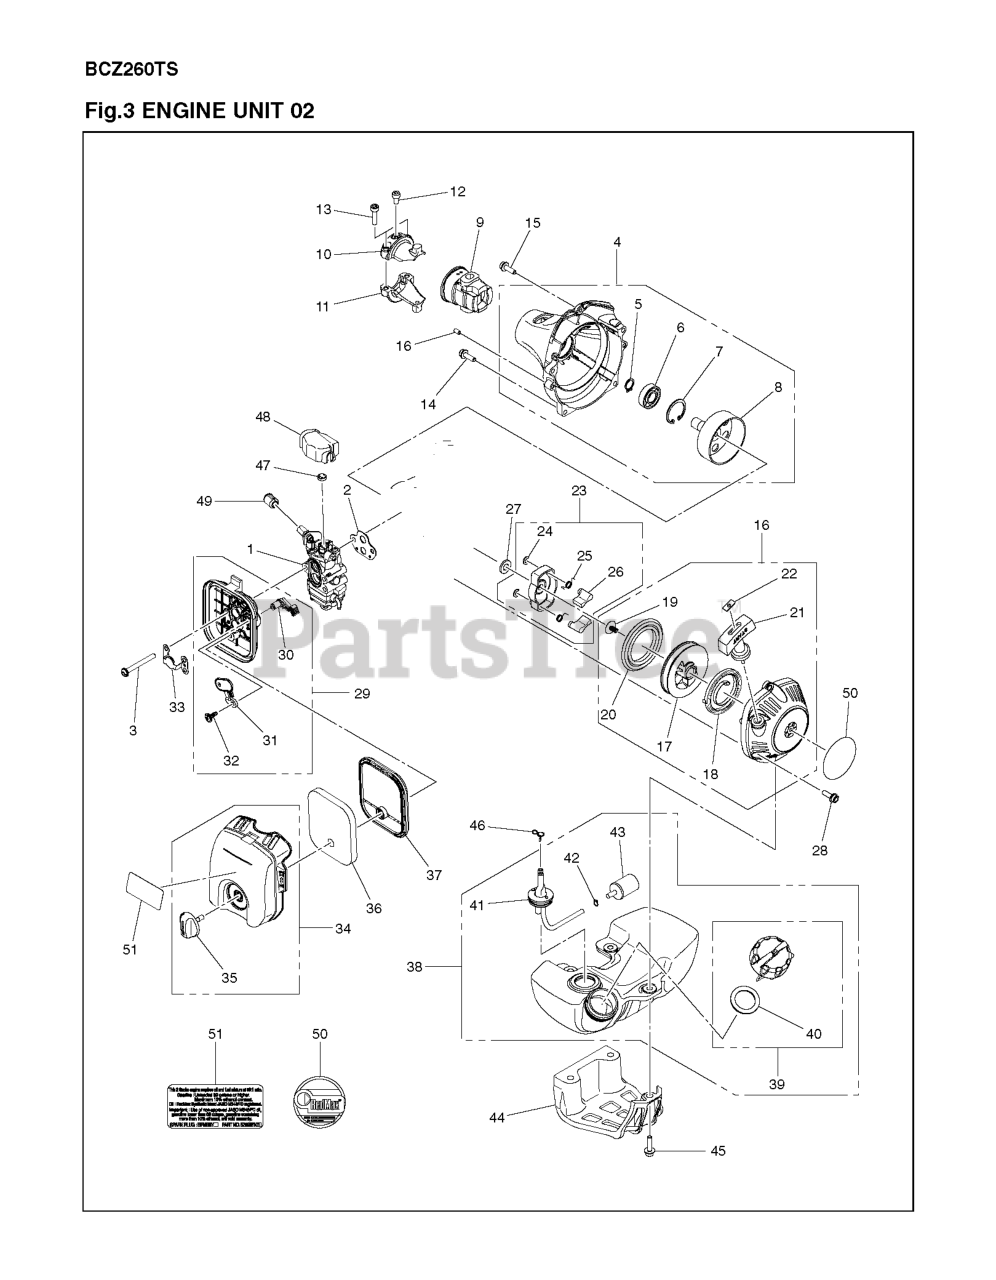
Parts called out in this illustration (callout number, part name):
1	CARBURETOR ASSY
2	GASKET CARBURETOR
4	HOUSING ASSY
8	CLUTCH DRUM
9	CUSHION UPPER
10	BRACKET UPPER M5X0.8
11	BRACKET LOWER
13	BOLT M5X20 T27
14	BOLT M5 X 16
16	STARTER ASSY
17	STARTER PULLEY
18	SPRING, SPIRAL
19	SCREW
20	ROPE
23	STARTER PULLEY ASSY
27	WASHER T2.0MM
28	BOLT M5 X 16
29	FILTER HOUSING ASSY
31	PLATE
34	COVER ASSY
35	Cleaner Knob
36	AIR FILTER
37	ELEMENT
38	ASSY TANK EVAP
39	TANK CAP
41	PIPE COMP
42	CLIP
43	FUEL FILTER
44	SKID PLATE
45	BOLT M5X25
46	CLIP
50	DECAL STARTER
51	DECAL , GASOLINE
